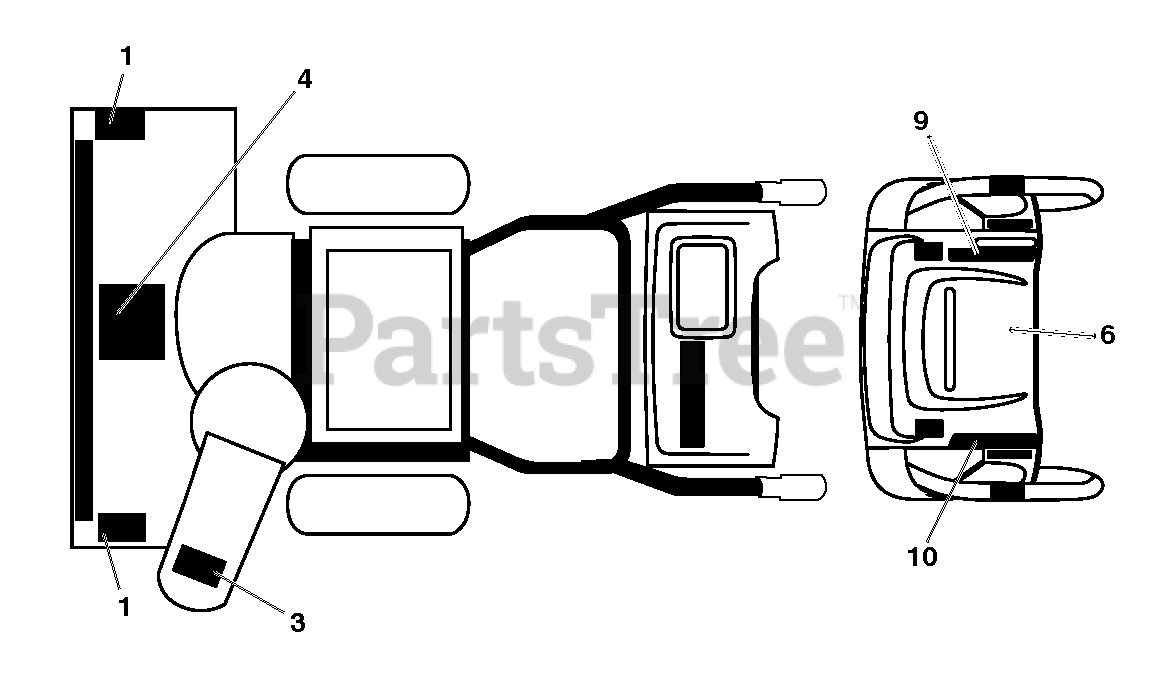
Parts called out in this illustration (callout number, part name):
1	DECAL.SNOWTHR.AUGER
3	DECAL.SNOWTHR.CHUTE.SAFETY
4	DECAL.SNOWTR.READ.OWN.MAN.E/F
6	DECAL, INSTRUCTION
10	Decal, Console LT SPD/LEV/P WRST
